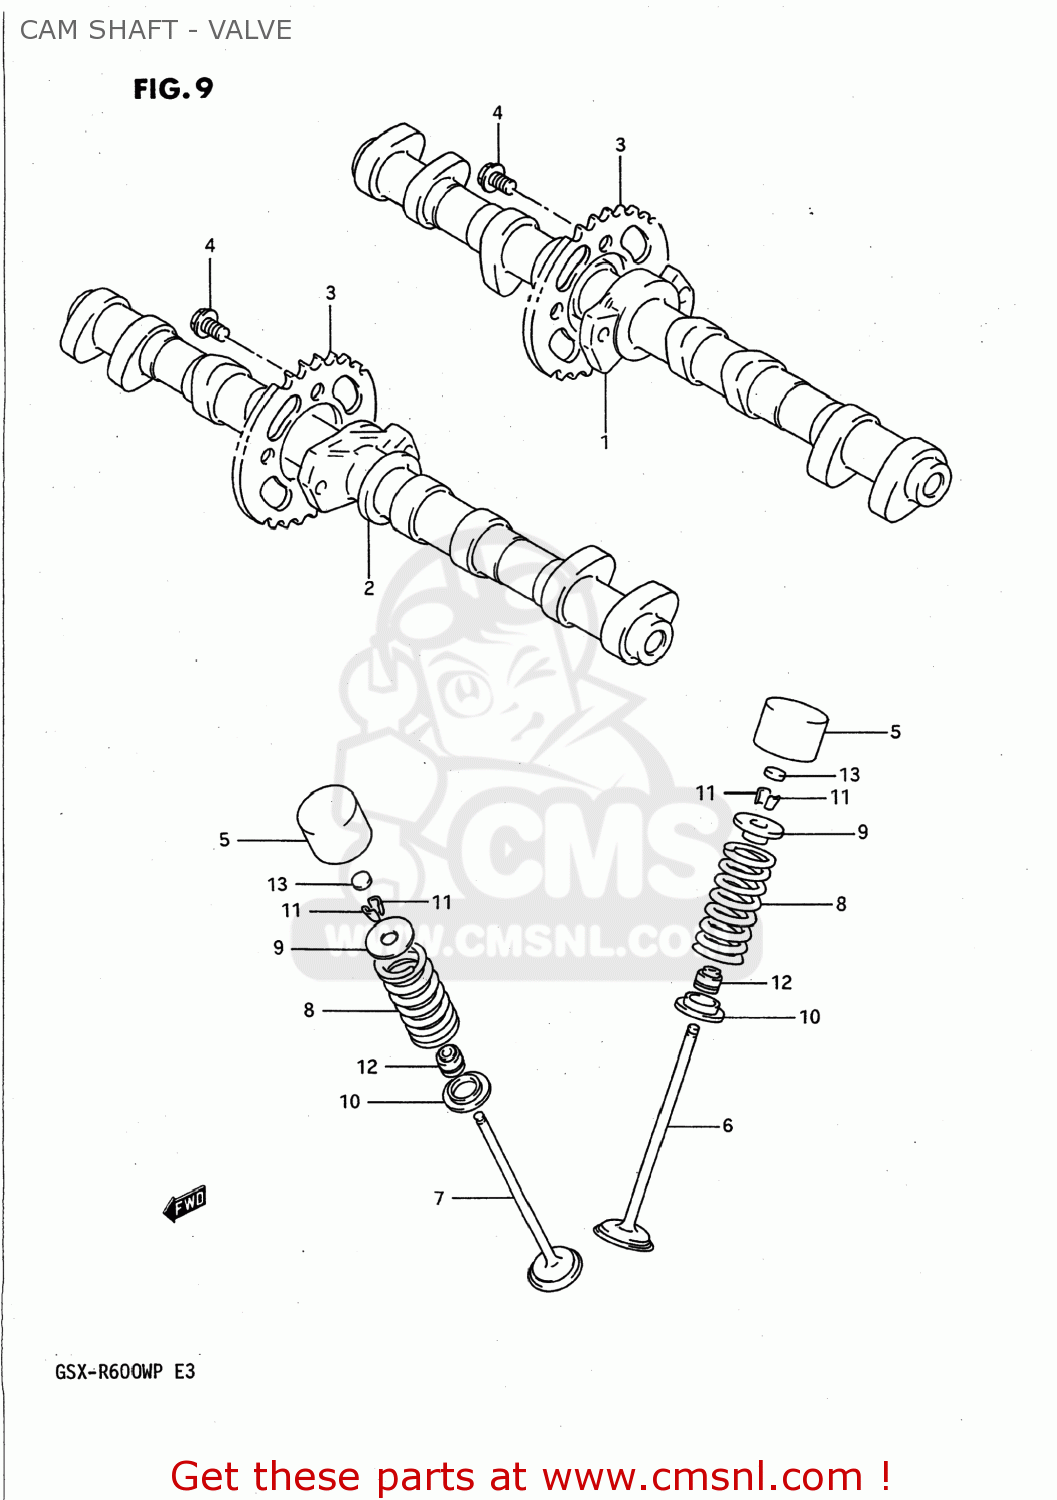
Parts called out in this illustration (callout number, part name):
1	CAMSHAFT,INTAKE
2	CAMSHAFT,EXHAUST
3	SPROCKET,CAMSHAFT
4	BOLT(7X11)
5	TAPPET
6	VALVE,INTAKE
7	VALVE,EXHAUST
8	SPRING,VALVE
9	RETAINER,VALVE SPRING
10	SEAT,VALVE SPRING
11	COTTER VALVE
12	SEAL,OIL(4.5X10X8)
13	SHIM,TAPPET
14	SHIM SET,TAPPET
15	CASE,TAPPET SHIM
